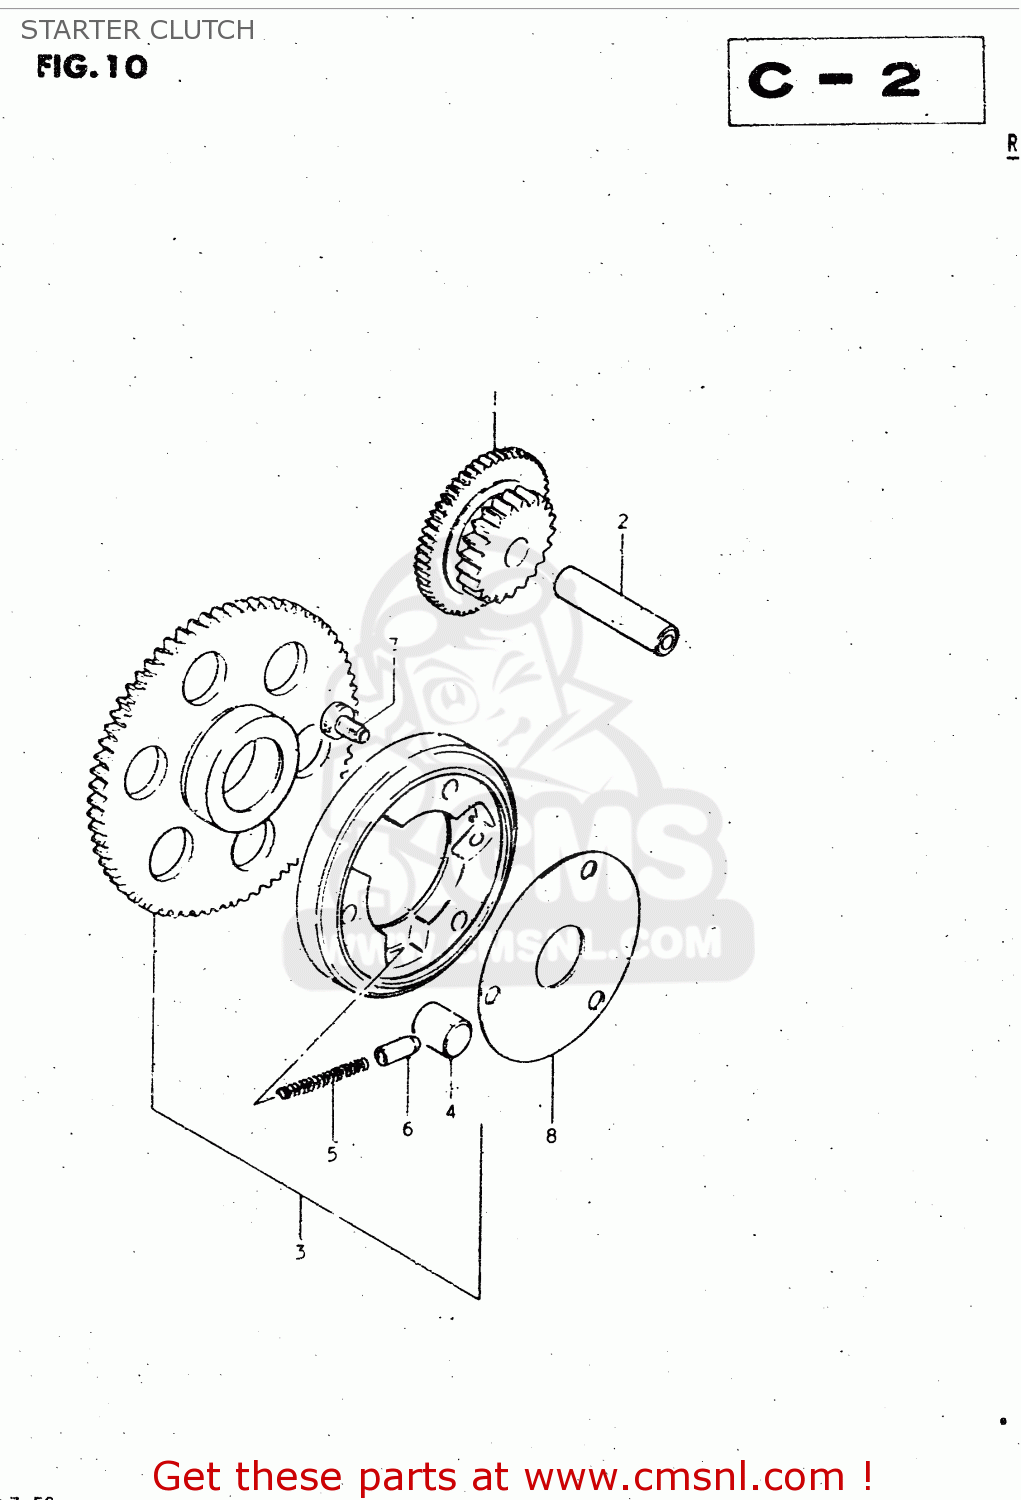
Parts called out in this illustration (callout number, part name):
1	GEAR,STARTER IDLE
2	PIN(7.4X13X56)
3	CLUTCH SET,STARTER
4	ROLLER(15X13)
5	SPRING
6	PIECE,PUSH
7	BOLT
8	SHIM,STARTER CLUTCH HUB
